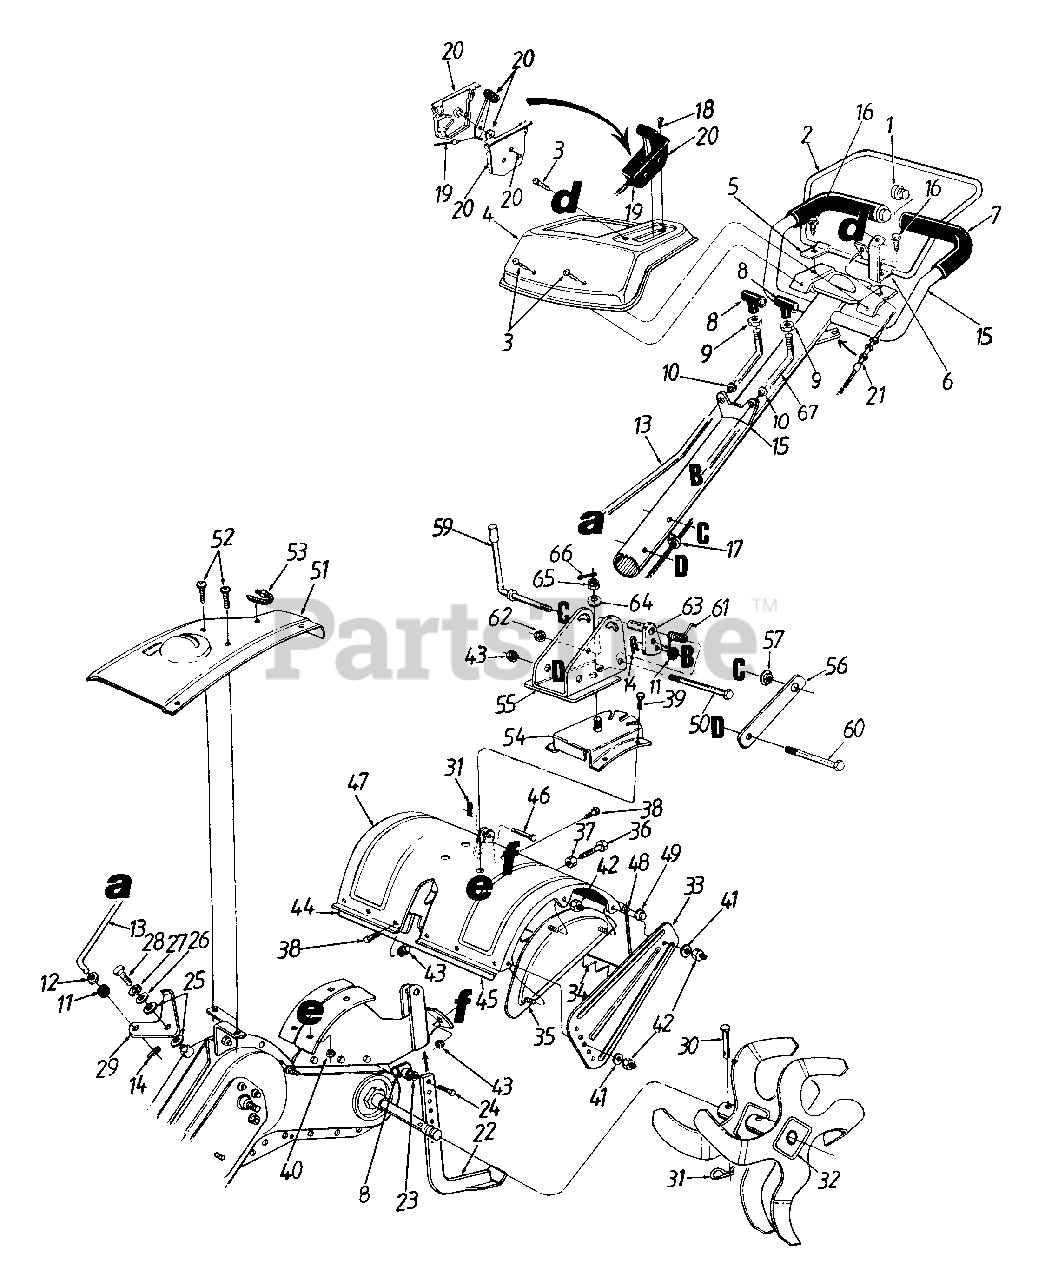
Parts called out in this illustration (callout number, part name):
1	Vinyl End Plug
3	Torx Mach. AB-Tap Scr. 1/4 x .62" Lg.
7	Grip
9	Hex Jam Nut 3/8-16 Thd.
10	Bushing 3/8" I.D.
11	Rubber Washer
12	Fl-Wash. .344" I.D. x .6" O.D.
13	Gear Shift Rod
14	Hairpin Clip
17	Cable Clip
18	Truss Mach. AB-Tap Scr. #10 x .5" Lg.
19	Throttle Wire 55" Lg.
20	Throttle Control Box Ass'y.
21	Clutch Cable
23	Fl-Wash. 3/8" I.D. x 5/8" O.D.
24	Hex Bolt 3/8-16 x .75" Lg.
25	Washer 1" O.D. (Hdn.)
26	Fl-Wash. .281" I.D. x .73" O.D.
27	L-Wash. 1/4" I.D.
28	Hex Bolt 1/4-20 x .62" Lg. (Gr. 5)
29	Shift Brkt.
30	Clevis Pin
31	Hairpin Clip
36	Hex Cap Bolt 5/16-18 x 1.25" Lg.
37	Hex Nut 5/16-18 Thd.
38	Hex Bolt 5/16-18 x .75" Lg.
39	Carriage Bolt 3/8-16 x 1" Lg.
40	Hex Ins. L-Nut 3/8-16 Thd.
41	Bell-Wash. .345" I.D. x .88" O.D.
42	Hex Cap L-Nut 5/16-18 Thd.
43	Hex Flange Top L-Nut 5/16-18 Thd.
46	Clevis Pin .375" Dia.
49	Cap Speed Nut
50	Hex Bolt 3/8-16 x 3" Lg.
52	Torx Mach. AB-Tap Scr. 1/4 x .6"
53	Wire Retainer Clip
57	Hex Flange Nut 3/8-24 Thd.
59	Handle Adjustment Crank
60	Hex Bolt 5/16-18 x 3" Lg.
61	Torsion Spring
62	Hex L-Nut 3/8-16 Thd.
63	Handle Swing Link
64	Bell-Wash. 5/8" I.D.
65	Hex Slotted Nut 5/8-18 Thd.
66	Cotter Pin 1/8" x 1-5/8"
67	Handle Adjustment Rod
